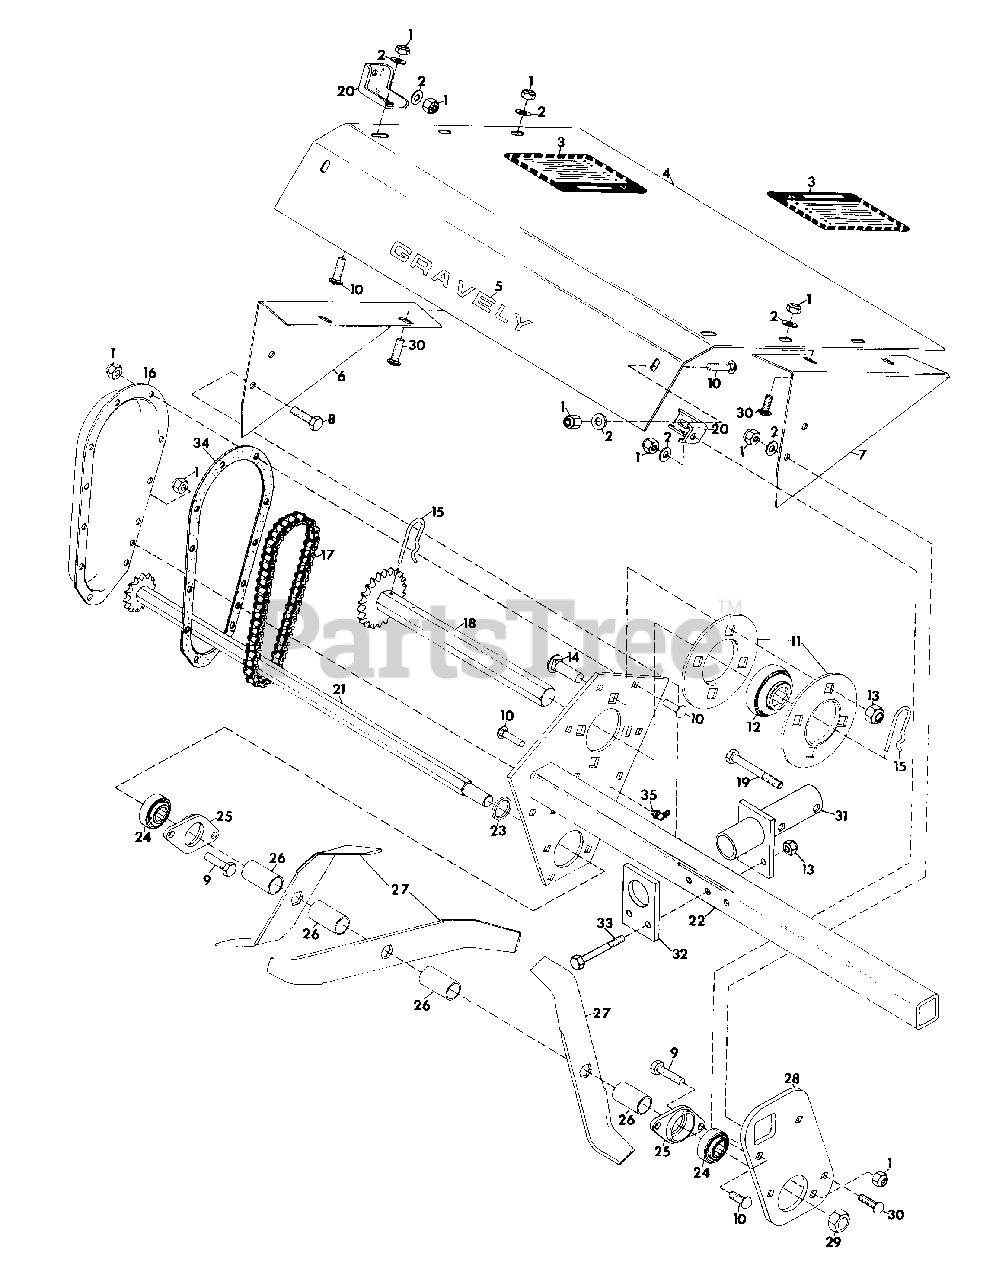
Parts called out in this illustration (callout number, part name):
1	NUT, LOCK 5/16-18
2	WASHER, FLAT .344X.688X.065
3	DECAL, CAUTION
4	SHIELD, DIRT
5	DECAL, GRAVELY
6	SHIELD, SIDE R.H.
7	SHIELD, SIDE L.H.
8	BOLT, HEX 5/16-18X.875
9	BOLT, HEX 5/16-18X1.25
10	BOLT, 5/16-18X.875 RD HD SQ NK
11	FLANGETTE, PRESSED STEEL
12	BEARING, HEX BORE
13	NUT, LOCK 1/2-13
14	BOLT, 1/2-13X1.25 RD HD SQ NK
15	PIN, DEPTH ADJUSTING
16	WELDMENT, SPROCKET COVER
17	CHAIN, ROLLER .625 PITCH
18	WELDMENT, DRIVE SPROCKET
19	BOLT, HEX 1/2-13X2.75
20	BRACKET, SHIELD
21	WELDMENT, TINE SHAFT
22	WELDMENT, FRAME
23	SPACER, SPROCKET 1.185X1.37X.202
24	BEARING, HEX BORE 1 INCH
25	HOUSING, BEARING
26	SPACER, TINE
27	TINE, HOE
28	PLATE, SUPPORT
29	NUT, JAM 1-8 HEX
30	BOLT, 5/16-18X.75 RD HD SQ NK
31	WELDMENT, SUPPORT PIPE
32	BRACKET, SUPPORT
33	BOLT, HEX 1/2-13X3.5
34	GASKET, SPROCKET COVER
35	FITTING, LUBE 90 DEG.
